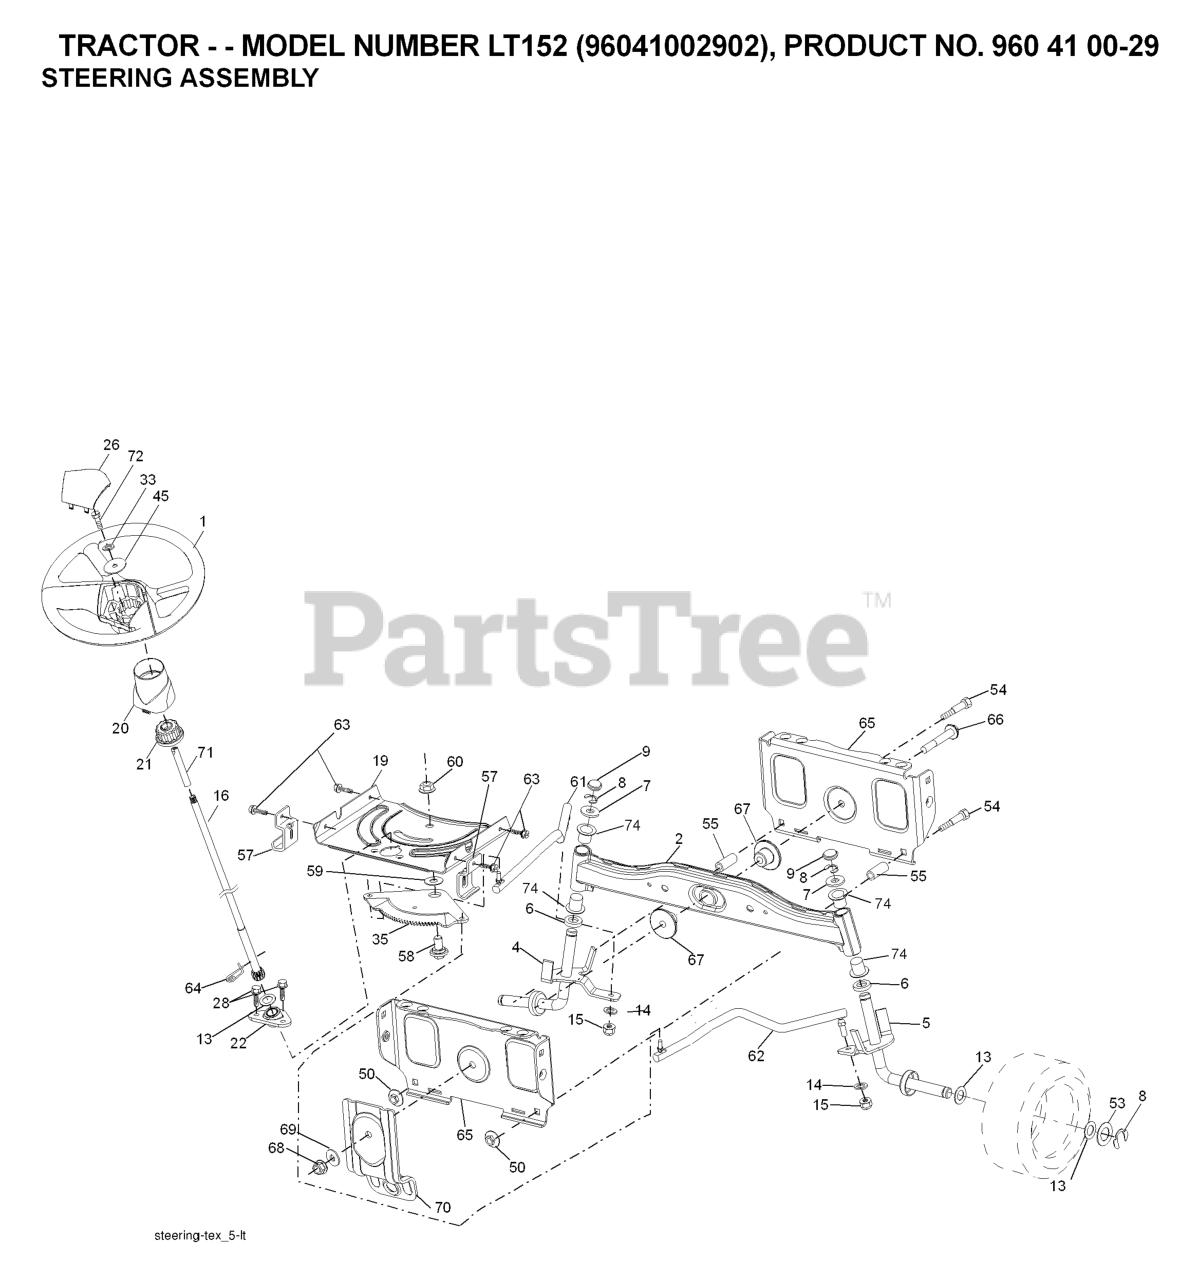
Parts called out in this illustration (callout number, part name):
1	WHEEL.STEERING.LEGEND2.GRY
2	AXLE.HALF.ASM.WELDED
4	SPINDLE.WELDED.LH.15"TEX
5	SPINDLE.WELDED.RH.15"T
6	THRUST WASHER
9	CAP.SPINDLE.BLACK
14	WASHER, LOCK 3/8
15	NUT CROWNLOCK 3/8-24
16	SHAFT.STEER.SPLINED.TEX.3 HIGH
19	PLATE.STEER.DDL.NLT/NG
20	BOOT, STEERING
21	ADAPTER, WHEEL STNG..
22	BUSHING.ASM.STEERING.A
26	INSERT.CAP.STRG.WH.GRAY
28	SCREW, 3/8-16X3/4
33	WASHER.LOCK.HVY.HLCL.SPR.5/16
35	GEAR.SECTOR.PLATE.DDL.
45	WASHER.11/32
50	NUT LOCK FLG 3/8-16 UNC
53	WASHER.HARDENED
55	SPACER.BRACE.AXLE (2 2)
57	BRACKET.UPSTOP.TEX
58	BOLT.SHOULDER.SECTOR.P
59	WASHER.THURST.SECTOR.S
60	NUT FLANGE LOCK 5/8-11
61	DRAGLINK.LH.BALLSTUD.D
62	DRAGLINK.RH.BALLSTUD.D
63	SCREW
64	RETAINER.CLIP.SPRING.S
65	BRACE.AXLE.FRONT.NLT/N
66	BOLT HEX FGHD 7/16-14 X 3 SERR
67	BUSHING.PM.FRONT AXLE
68	NUT.LOCK.FLANGE.7/16
69	WASHER.1.5X.505X.118
70	BRKT.DECK.SUSPENSION.F
71	SHAFT EXTENSION STEERING
72	BOLT YT
74	BRNG T
